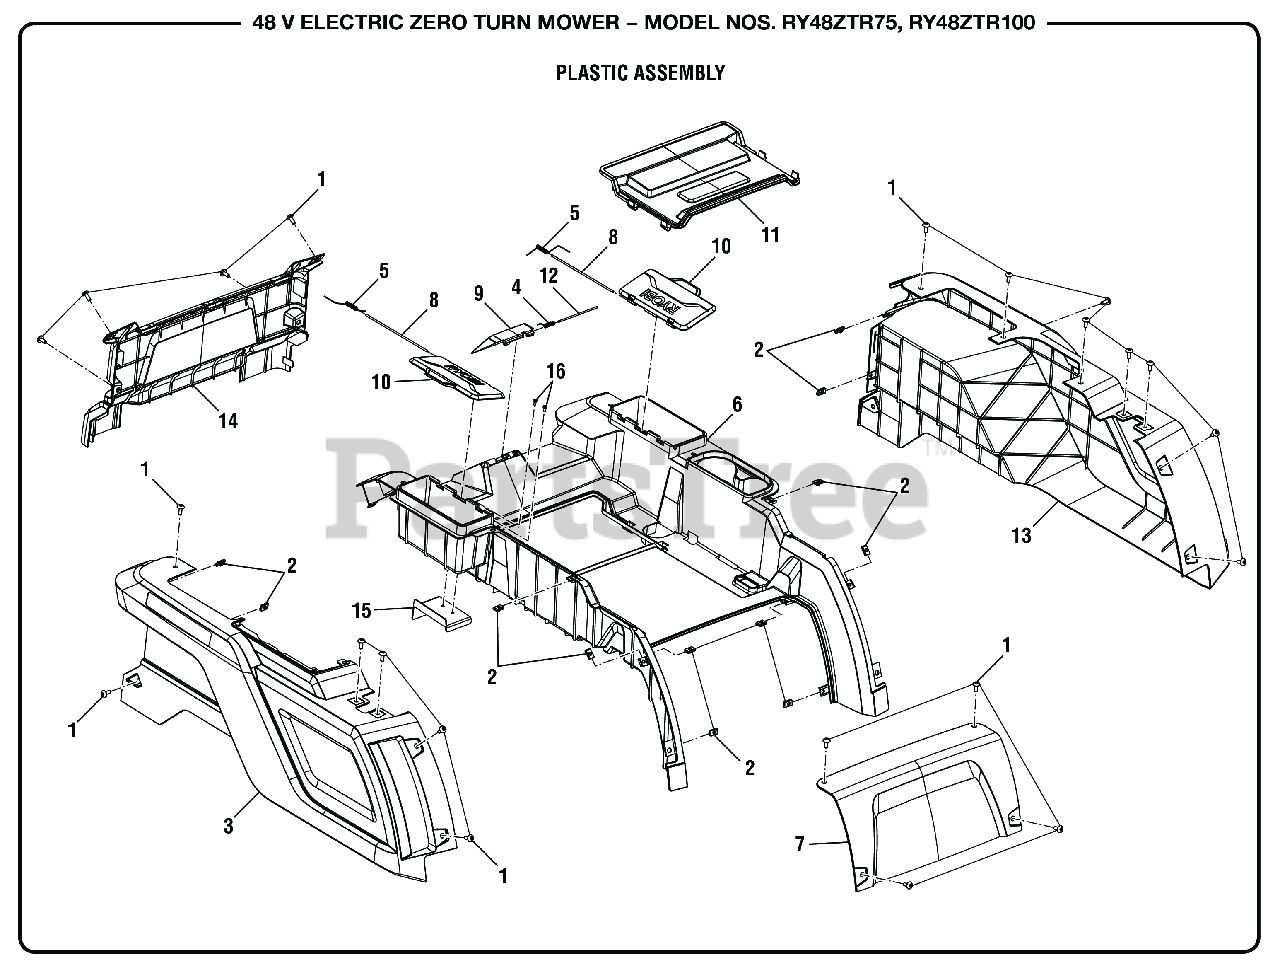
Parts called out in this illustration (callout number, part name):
1	Screw (M6 x 10 mm, Soc. Button Hd.)
2	Clip-On Nut (M6)
3	Right Trim Cover
4	Charger Port Door Spring
5	Storage Box Spring
6	Center Trim Cover
7	Front Access Panel
8	Storage Box Hinge Pin
9	Charger Port Door
10	Storage Box Lid
11	Center Access Panel
12	Charger Port Door Hinge Pin
13	Left Trim Cover
14	Rear Trim Cover
15	Main Relay Guard
16	Screw (M4 x 10 mm, Pan Hd.)
